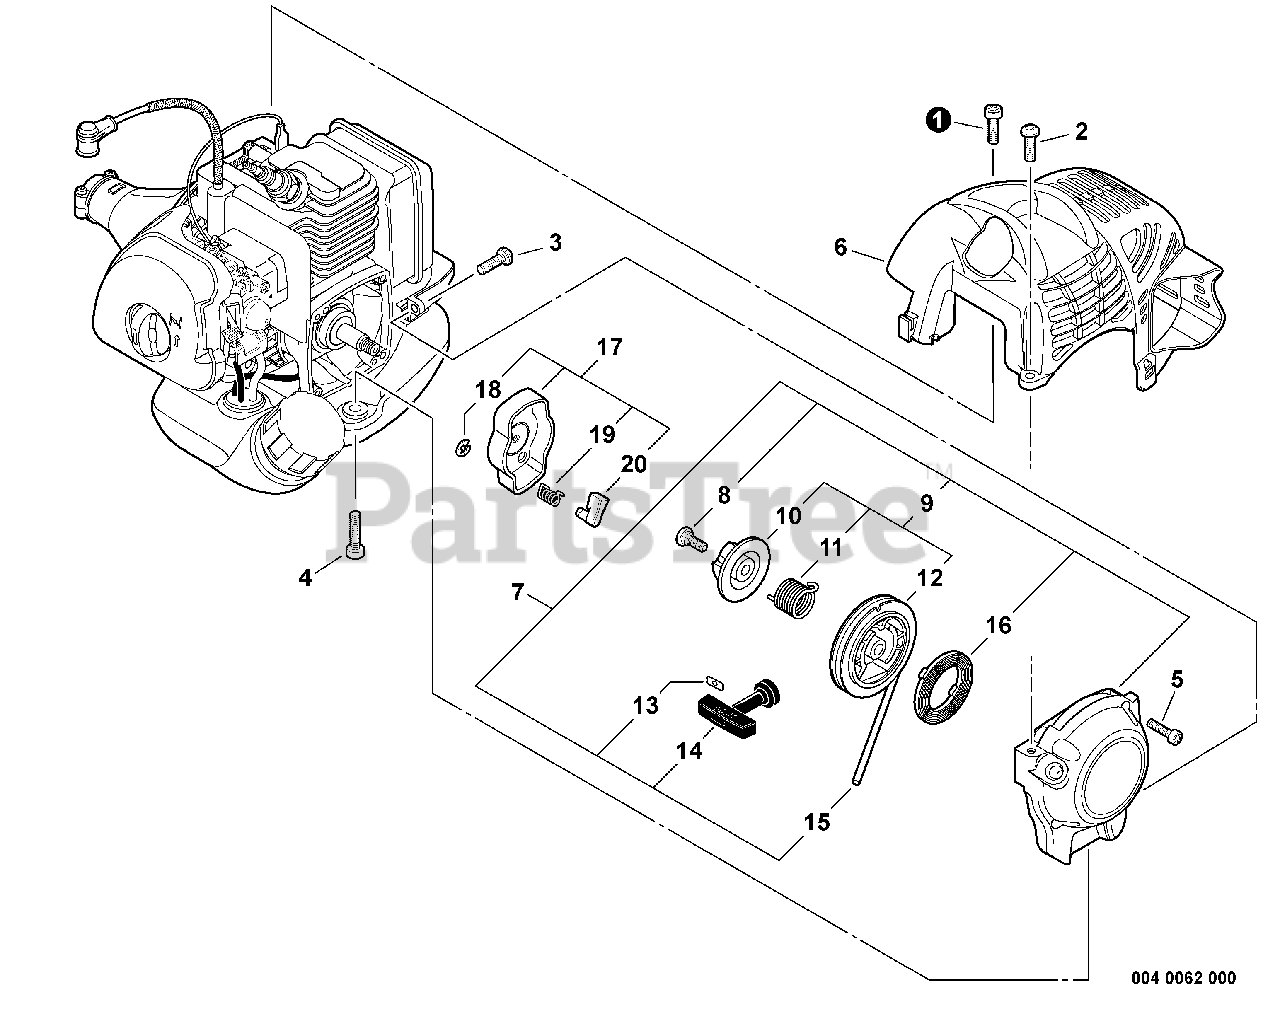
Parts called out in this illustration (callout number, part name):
1	BOLT, TORX 5×16
2	BOLT, TORX 5×16
3	BOLT, TORX 5×16
4	BOLT, TORX 5×25
5	BOLT, TORX 4×16
6	COVER, ENGINE
7	STARTER ASSY, RECOIL
8	SCREW
9	REEL/CAM PLATE SET
10	PLATE, CAM
11	SPRING, TORSION
12	REEL, ROPE
13	RETAINER, ROPE
14	GRIP, STARTER
15	ROPE, STARTER
16	SPRING, RECOIL
17	PAWL ASSY, STARTER
18	E-RING 4
19	SPRING, RETURN
20	PAWL, STARTER
